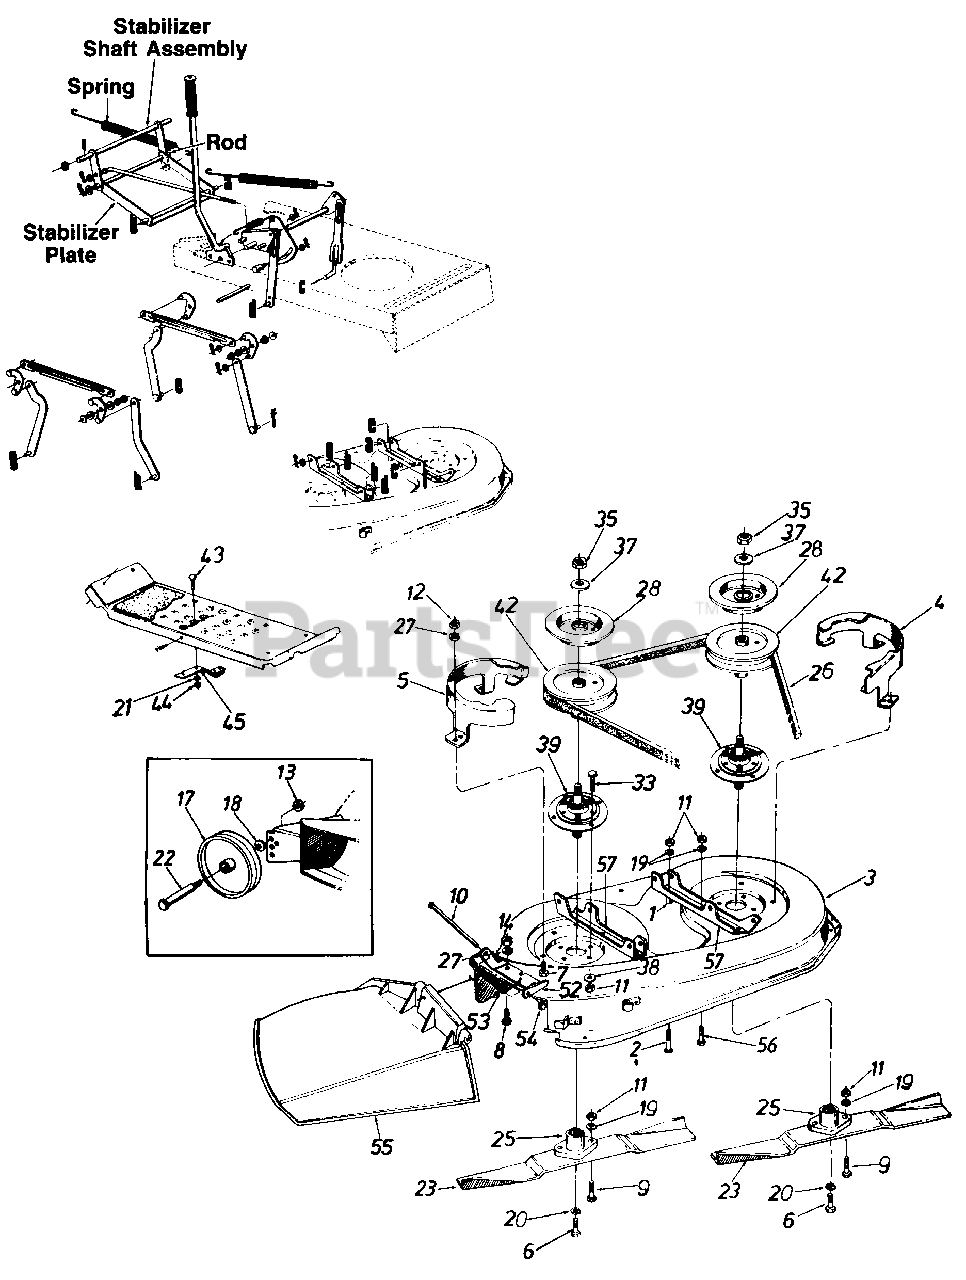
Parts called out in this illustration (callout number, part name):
1	Spacer.33" l.D. x .88"
2	Hex Bolt 5/16-24 x 1.25" Lg.
3	38" Deck Ass'y. w/Deck Wheels
7	Hex Bolt 1/428 x .62" Lg.
8	Truss Mach. Scr. 1/420 x .77"
9	Hex Bolt Special 5/16-24 x 1.0"
10	Hinge Pin
11	Hex Nut 5/16-24 Thd.
12	Hex Nut l/4-28 Thd.
13	Hex Top L-Nut 3/8-16 Thd.
14	Hex Nut 20 Thd.
17	Deck Wheel-5n
18	Bell-Wash. .40" l.D. x .88" O.D.t
19	L-Wash. 5/16" l.D.
20	L-Wash. 3/8" l.D.-H.D.
21	L-Wash. 1/4" l.D.
22	Shld. Bolt .498" Dia. x 1.53n
23	High-Lift Blade
25	Blade Adapter
26	V-Belt
27	Bell-Wash. 1/4" I.D.
28	Brake Disc
33	Hex Bolt 5/1-24 x .75" Lg.
35	Hex Jam Nut 5/8-18 Thd.
37	L-Wash. 5/8" l.D.
38	L-Wash. 5/16" l.D.
39	Blade Spindle Ass'y. Comp.
42	5" Dia. Pulley
43	Carr. Bolt 1/4 20 x .62n
44	Hex Nut 1/4 20 Thd.
45	Blade Brake Ass'y.
52	Hinge Mtg. Brkt.
53	Torsion Spring
55	Chute Ass'y. Comp.
56	Hex Bolt 5/16-24 x 75" Lg.
